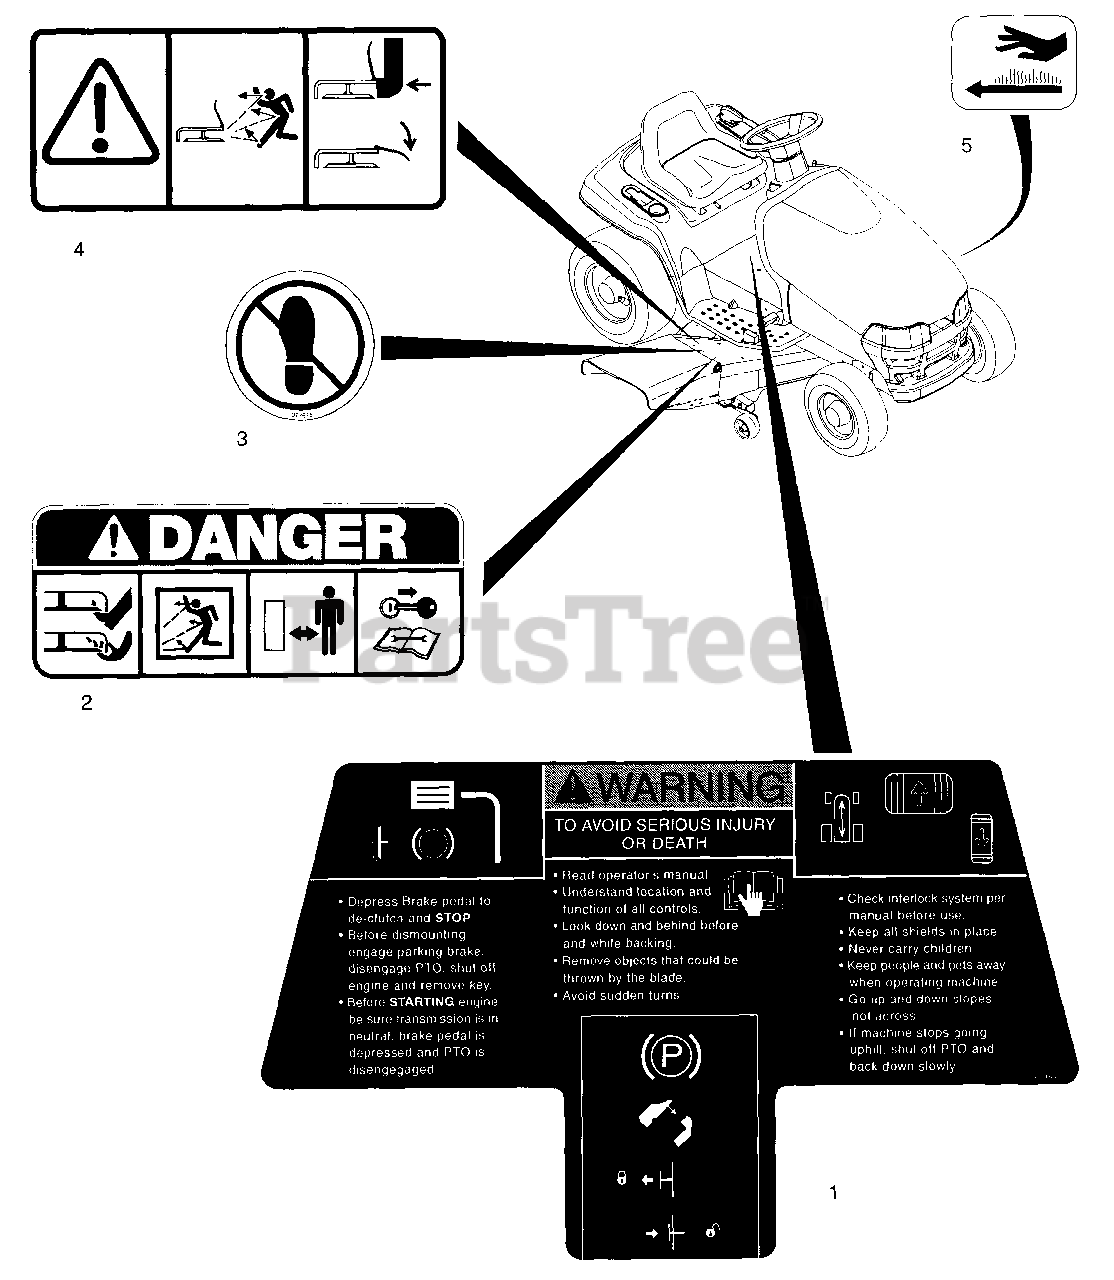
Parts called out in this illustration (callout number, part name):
1	DECAL - OPERATING INSTRUCTIONS
2	DECAL- MOWER PAN
3	NO STEP DECAL
4	DECAL- DISCHARGE
5	DECAL- HOT SURFACE SYMB.
